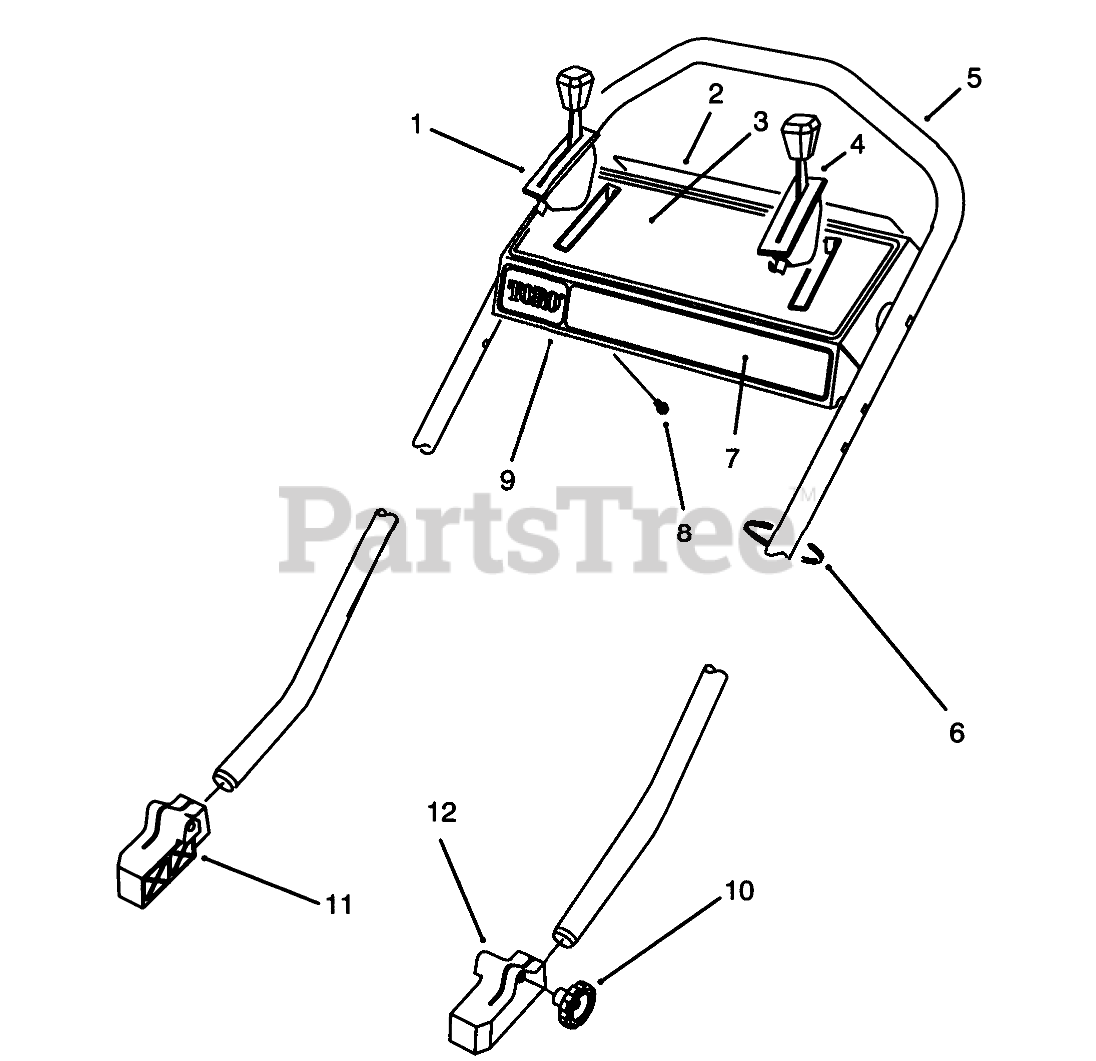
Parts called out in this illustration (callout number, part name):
1	GROUND SPEED CONTROL
2	DECAL - PANEL, REAR
3	DECAL-INSTRUCTION OHV
4	THROTTLE CONTROL
5	HANDLE PVC DIP
6	TIE-CABLE
7	DECAL - PANEL 2 CYCLE
8	SCREW-HWHTF
9	Control Panel Assembly (Incl. Ref. #2, 3, & 7)
11	MOUNT-HANDLE, RH
12	MOUNT-HANDLE, LH
